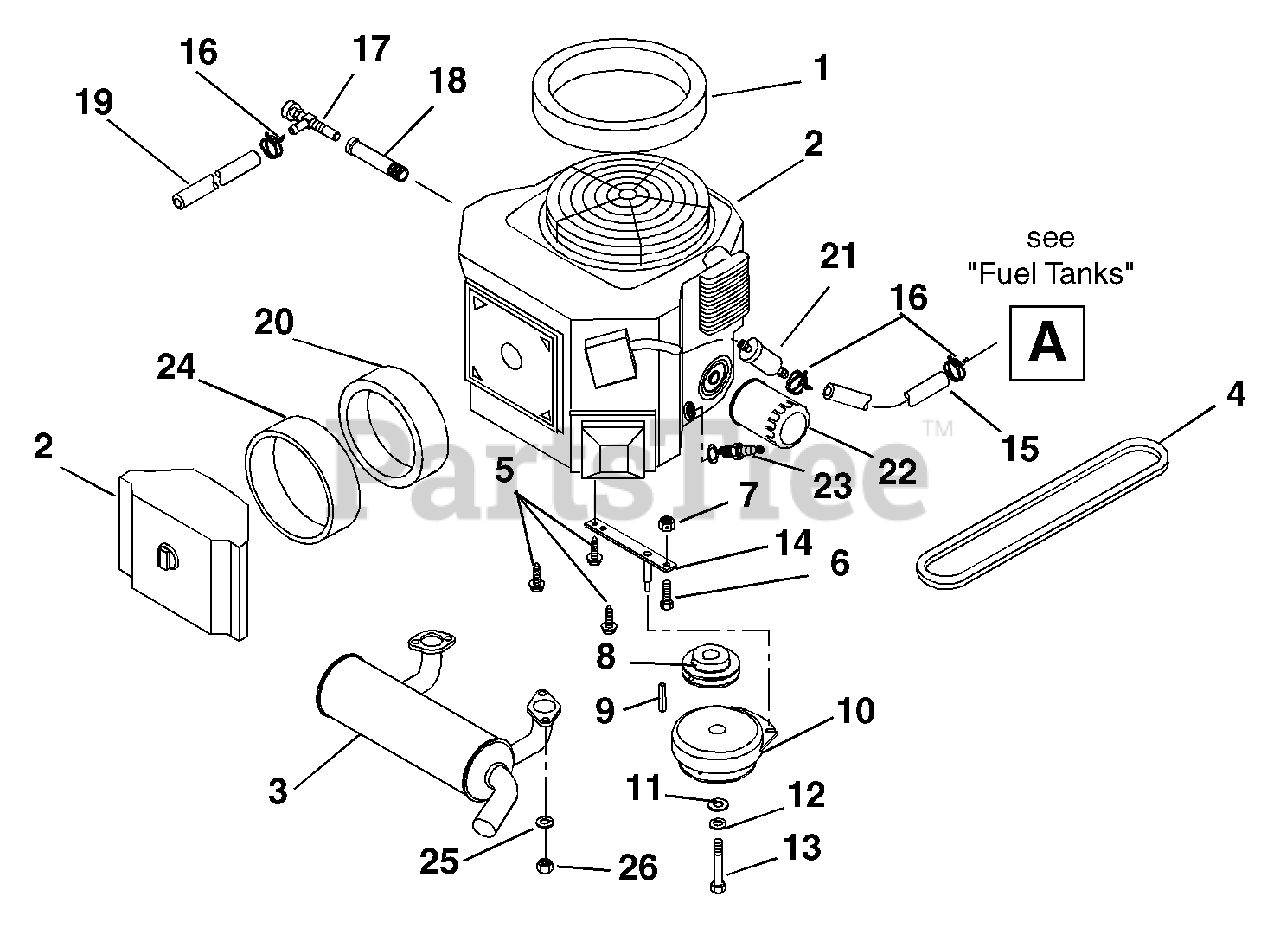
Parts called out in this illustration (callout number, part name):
1	Seal-Foam
2	25HP-Kohler Command Vertical (020)
2	Engine, 25 HP Kawasaki (029, 030)
2	Engine, Kawasaki 19HP (034)
2	Engine, Kawasaki 23HP (035)
3	Muffler, Kohler Command (020)
3	Muffler- Kawasaki (029, 030, 034, 035)
4	V-Belt, A-Section 28.29 x .531
5	Screw-Tapping Hex-Washer-Head .38-16 x 1.00
6	Bolt-Hex .31-18 x 1.75 Grade 5
7	Nut-Locking-Center .31-18
8	Pulley-V 4.00 x 1.125 with Key
9	Key-Square .25 x 1.00 x .25
10	Clutch, Electric
11	Washer-Flat-Steel .515 x 1.625 x .250
12	Washer-Locking .44 x .109
13	Bolt-Hex .44-20 x 3.00 Grade 5
14	Anchor-Clutch
15	Gas Line-Bulk 1/4" ID
16	Hose-Clamp
17	Cock-Oil Drain
18	Adapter-Oil Drain
19	Gas Line-Bulk 1/4" ID
20	Air Filter (029, 030, 034, 035)
20	Air Filter (020)
21	Fuel Filter
22	Oil Filter (020)
22	Oil Filter (029, 030, 034, 035)
23	Spark Plug (020)
23	Spark Plug (029, 030, 034, 035)
24	Element, Precleaner (029, 030, 034, 035)
24	Element, Pre-Cleaner (020)
25	Washer-Lock .31 x .078 Regular
26	Nut-Hex M8-1.25
